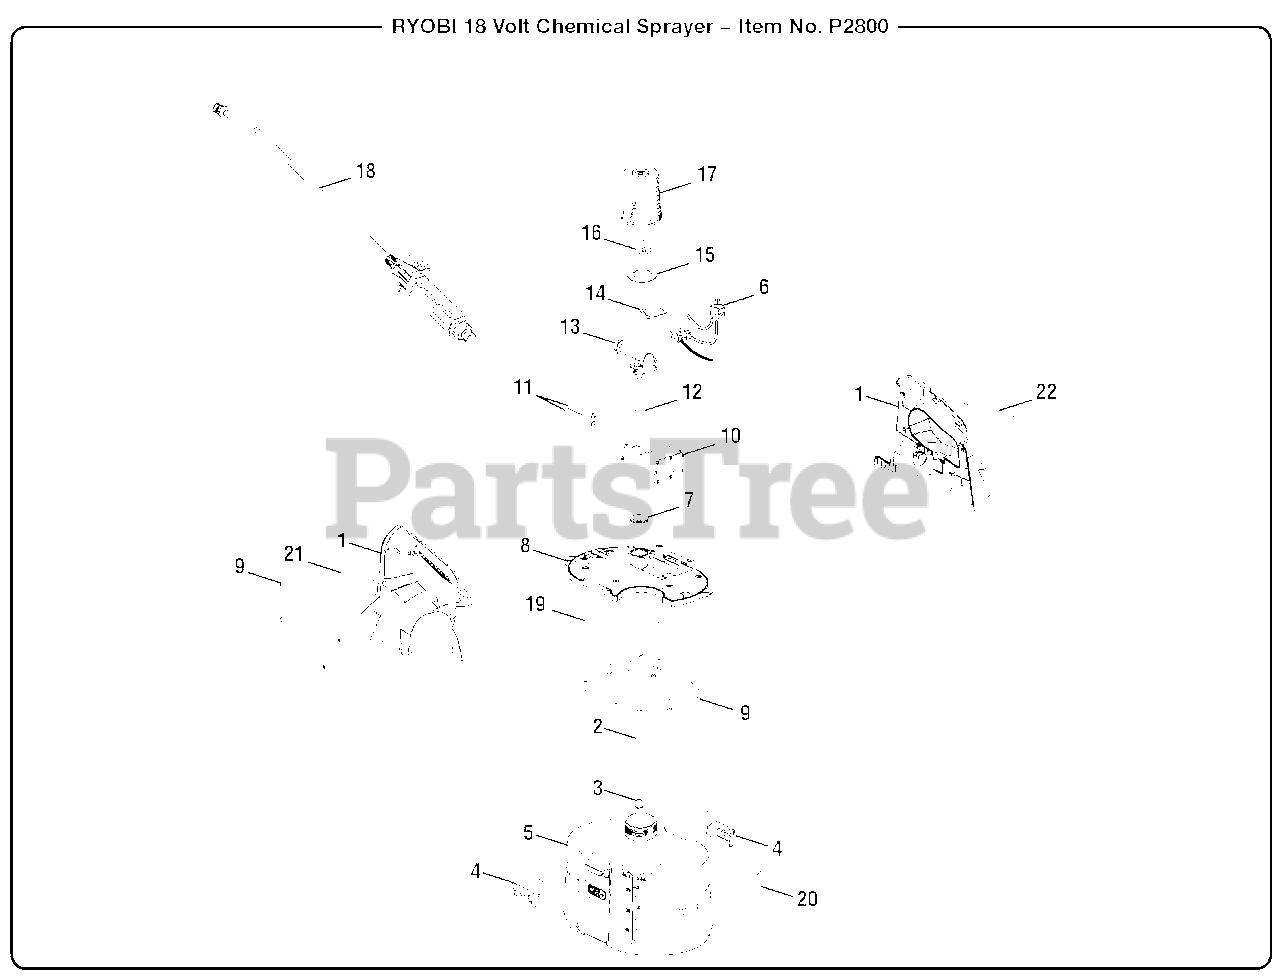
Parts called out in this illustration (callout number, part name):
1	Handle Housing Assembly
2	Tube (short)
3	Drink Head
5	Water Tank Assembly
6	Wiring Harness
7	Rubber Seal
8	Housing Deck Assembly
9	Screw (need size)
10	Pump Diaphram
11	Tube (long)
13	Connector
16	Rubber Umbrella Pin
17	Tank Cap
18	Trigger Handle Assembly
19	Data Label
20	Warning Icon Label
21	Notice Label (A)
22	Notice Label (B)
